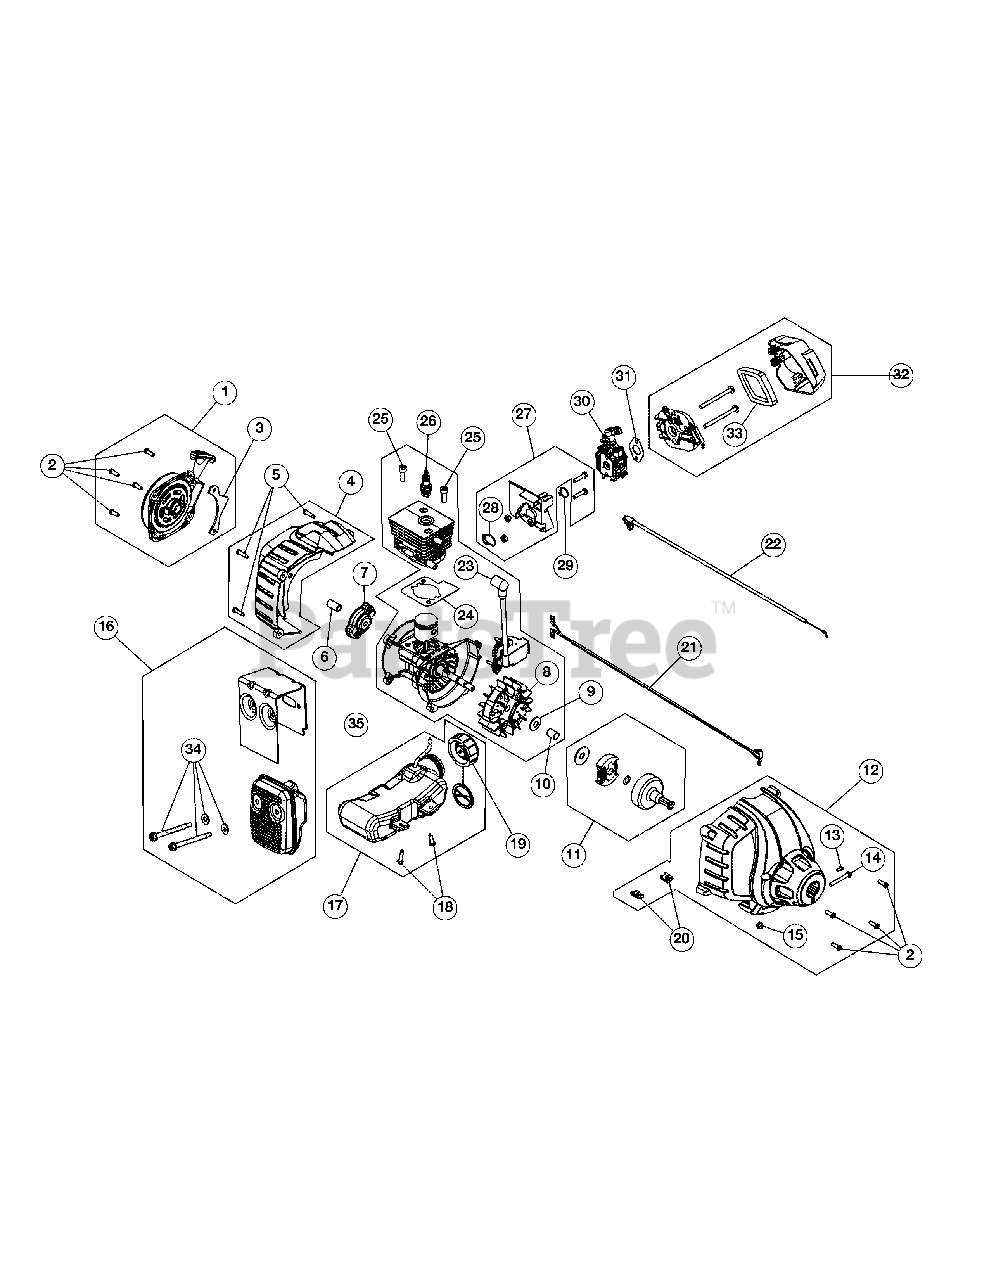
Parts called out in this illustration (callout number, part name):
1	Rear Cover Assembly (Incl. 2 & 3)
2	Starter Screw
3	Starter Assembly Guard (Incl. 2)
4	Rear Engine Cover (Incl. 5)
5	Cover Screw
6	Adapter
7	Pawl Assembly
8	Flywheel Assembly
9	Washer
10	Spacer
11	Clutch Assembly
12	Clutch Cover Assembly (Incl. 2, 13-15 & 20)
13	Anti-Rotation Screw
14	Clamp Screw
15	Clamp Nut
16	Muffler Assembly (Incl. 35)
17	Fuel Tank Assembly (Incl. 18 & 19)
18	Tank Screw
19	Fuel Cap
20	U-Shaped Nut
21	Lead Wires
22	Throttle Cable
23	Module Assembly
24	Cylinder Gasket
25	Cylinder Bolt
26	Spark Plug
27	Insulator Assembly (Incl. 28)
28	Insulator O-Ring
29	Carburetor O-Ring
30	Carburetor
31	Carburetor Gasket
32	Aircleaner Assembly (Incl. 33)
33	Aircleaner Filter
34	Muffler Screw
35	Short Block Assembly
